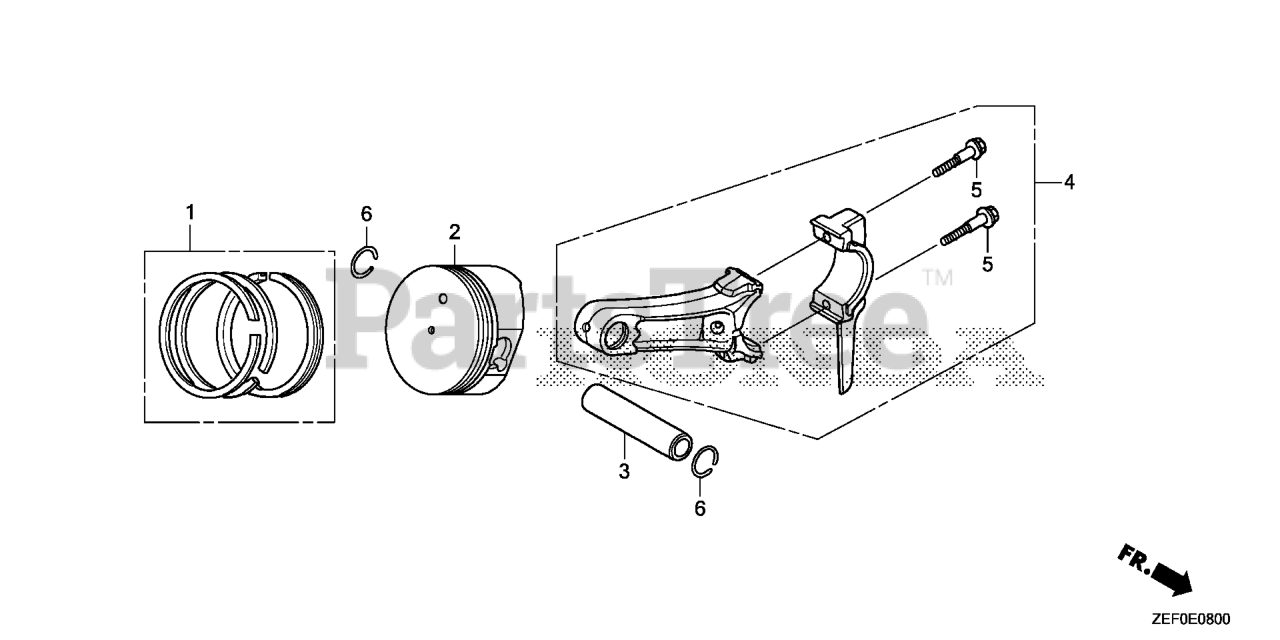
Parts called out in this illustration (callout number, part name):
1	RING SET, PISTON (STD) (TPR)
1	RING SET, PISTON (STD) (RIKEN)
1	RING SET, PISTON (0.25) Use from Engine SN 1314913.
1	RING SET, PISTON (0.25) (RIKEN)
1	RING SET, PISTON (0.50) (TPR)
1	RING SET, PISTON (0.50) (RIKEN)
1	RING SET, PISTON (0.75) Use from Engine SN 1314913.
1	RING SET, PISTON (0.75) (RIKEN)
2	PISTON (STD)
2	PISTON (0.25)
2	PISTON (0.50)
2	PISTON (0.75)
3	PIN, PISTON
4	ROD ASSY., CONNECTING (UNDER SIZE) (NOT AVAILABLE)
4	ROD ASSY., CONNECTING
5	BOLT, CONNECTING ROD
6	CLIP, PISTON PIN (18MM)
